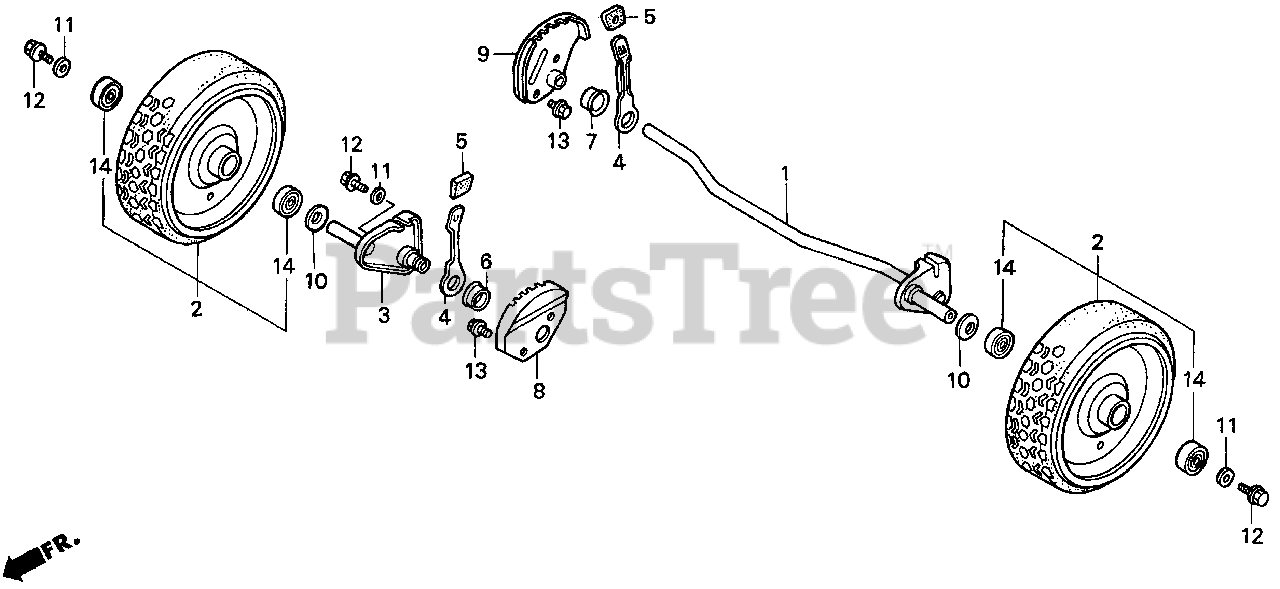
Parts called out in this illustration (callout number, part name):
1	SHAFT, FR. AXLE
2	WHEEL (9")
3	ARM, R. FR. ADJUSTER
4	PLATE, FR. ADJUSTER
5	GRIP, ADJUSTER
6	DUST SEAL, R.
7	DUST SEAL, L.
8	PANEL, R. FR. ADJUSTER (NOT AVAILABLE)
9	PANEL, L. FR. ADJUSTER (NOT AVAILABLE)
10	WASHER, WHEEL
11	WASHER, RR. ENGINE MOUNTING
12	BOLT, FLANGE (8X16)
13	BOLT, FLANGE (6X12)
14	BEARING, RADIAL BALL (6002UU)
